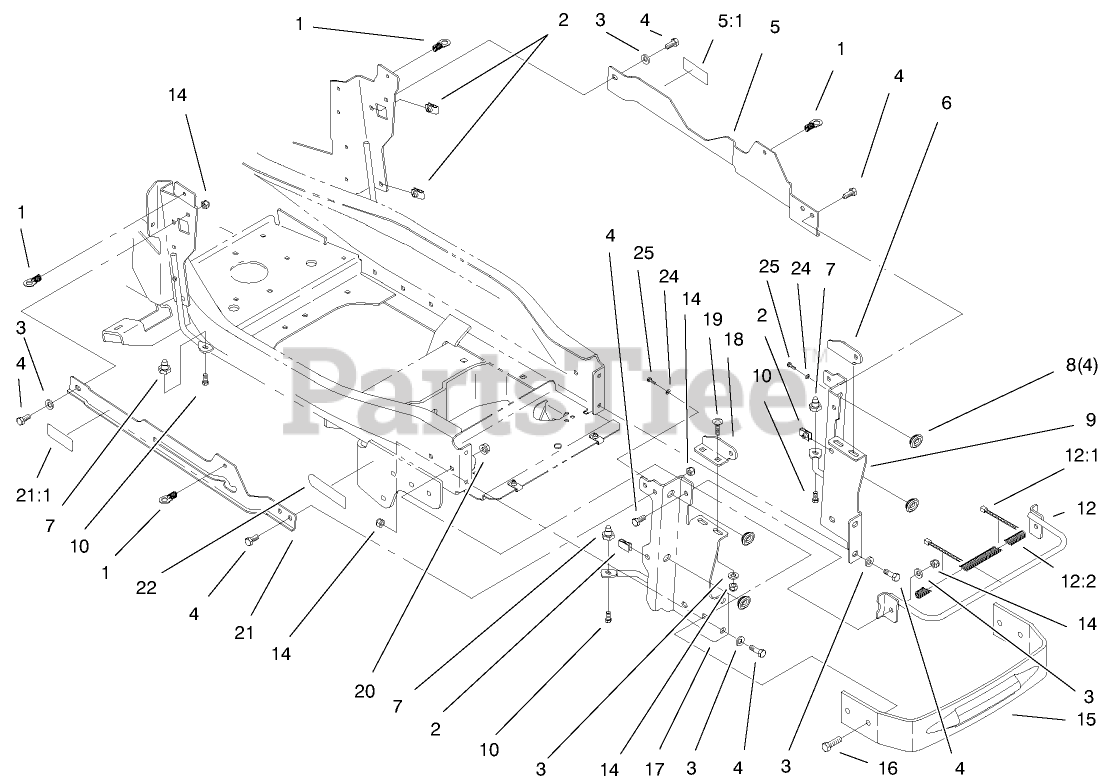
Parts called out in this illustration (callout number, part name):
1	LATCH ASM
3	WASHER-PLAIN
4	SCREW-HH
5	Support ASM (Only On: 73541)
5:1	DECAL-WARNING
5:1	DECAL - WARNING
6	BRKT-LOWER HINGE LH
7	MOUNT-SIDEPANEL
8	GROMMET
10	SCREW-PLASTITE
12	ASSEMBLY - HOOD SUPPORT
12:1	COVER-BRACE
12:2	TIE-CABLE
14	NUT-LOCK, NI
16	SCREW-HH
17	SUPPORT-HOOD, RH
18	BRACKET-LOWER HINGE RH
19	SCREW-CARR
20	NUT-LOCK, NI
21	Support ASM (Only On: 73541)
21:1	DECAL-WARNING
21:1	DECAL - WARNING
22	DECAL-ATTACH A-MATIC
24	WASHER-FLAT
25	SCREW-THD FORM, HWH
26	CLAMP-TUBE
27	DECAL-SURFACE, HOT
